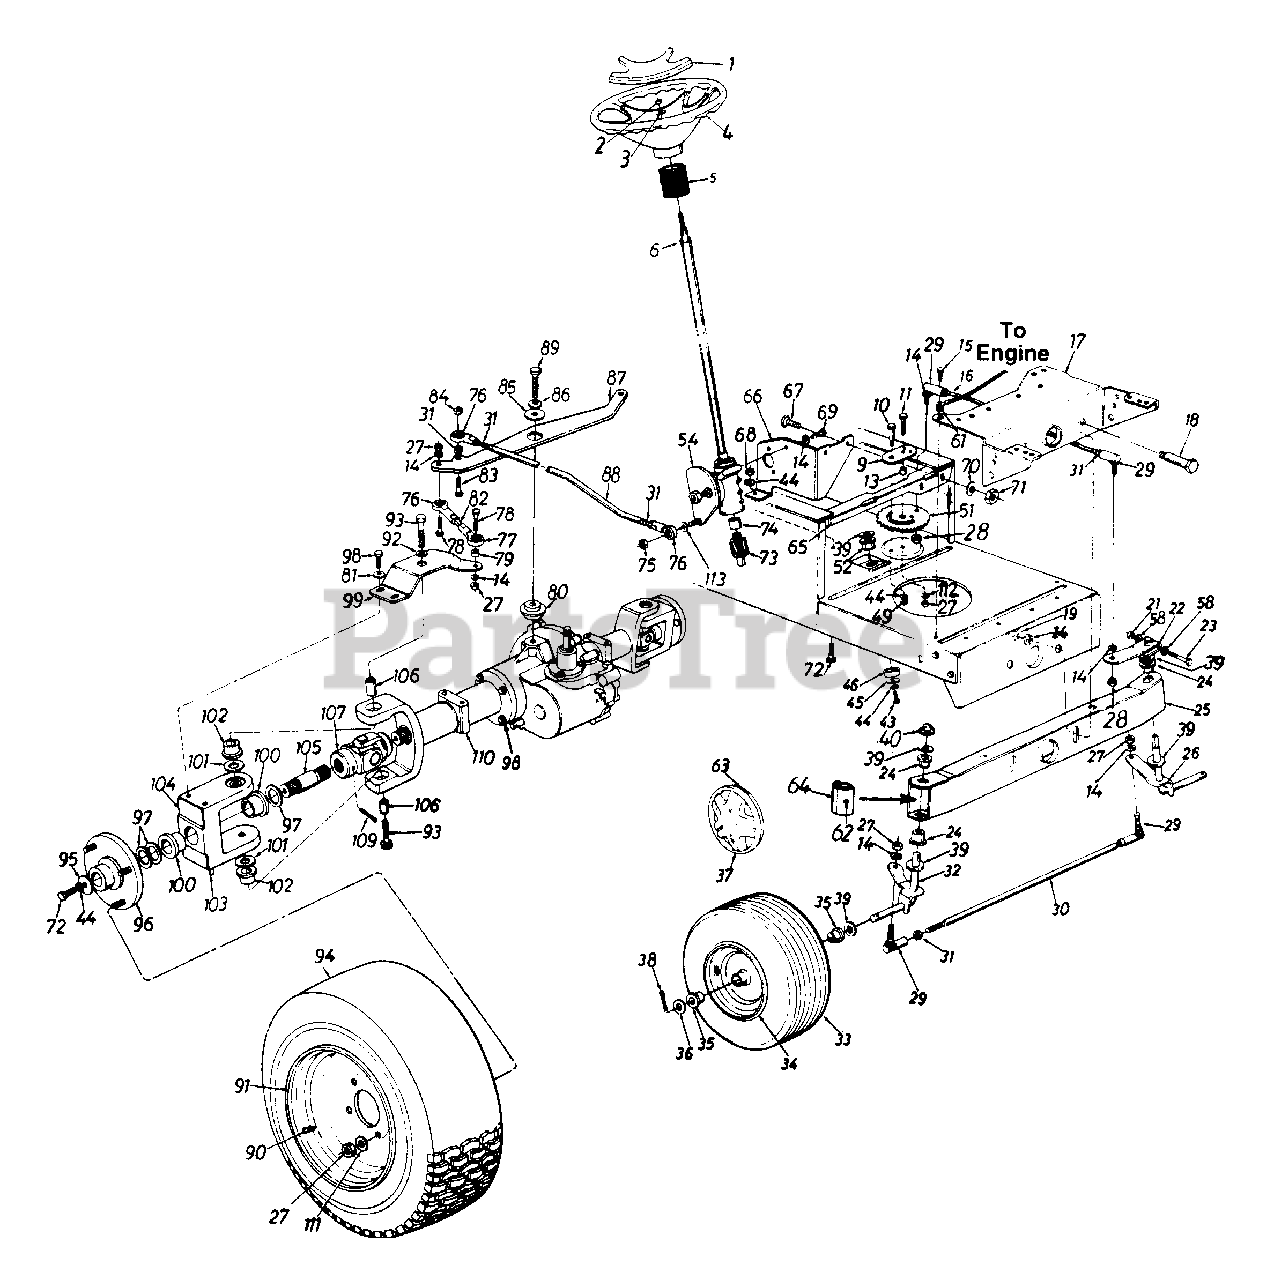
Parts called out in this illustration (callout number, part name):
1	Steering Wheel Cap
2	Hex L-Nut 5/16-24 Thd.
3	Belleville Wash. .345" I.D.
4	Steering Wheel
5	Steering Bellow
6	Steering Shaft Ass'y.
9	Retainer Plate
10	Shoulder Bolt .437" Dia. x .35" Lg. 5/16-18 Thd.
11	Hex Bolt 3/8-24 x 1.0" Lg. (Grade 5)
13	Spacer .380" I.D. x .625" O.D. x .227"
14	L-Wash. 3/8" I.D.
15	Hex Wash. Hd. Self-Tap Scr.
16	Steering Drag Link
18	Shoulder Bolt .498" Dia. x 2.04" Lg. 3/8-16 Thd.
19	Hex Nut 3/8-16 Thd.
21	Hex Cent. L-Nut 5/16-24 Thd.
22	Steering Arm Front Axle
23	Hex Bolt 5/16-24 x 2.00" Lg. (Grade 5)
24	Hex Flg. Brg. .634" I.D.
26	Front Axle Ass'y. - L.H.
27	Hex Nut 3/8-24 Thd.
28	Hex Jam Nut 3/8-24 Thd.
29	Ball Joint 3/8-24 Thd.
31	Hex Jam Nut 3/8-24 Thd.
32	Front Axle Ass'y. - R.H.
35	Ball Bearing
36	Fl-Wash. .635" I.D. x 1.59" O.D.
37	Front Hub Cap
38	Cotter Pin 1/8" Dia. x 1.25" Lg.
39	Fl-Wash. .640" I.D. x .24" O.D.
43	Hex L-Bolt 5/16-18 x .62"
44	L-Wash. 5/16" I.D.
45	Fl-Wash. .33" I.D. x 1.25" O.D.
46	Spacer (Plastic)
49	Hex L-Nut 5/16-18 Thd.
51	Steering Gear Segment
52	Hex Flg. Brg. .634 I.D.
54	Steering Ass'y. Comp.
58	Wave Wash. .32" I.D. x .62"
61	Ext. L-Wash. 5/16" I.D.
62	Grease Fitting
63	Spring Clip
64	Pivot Bar End Cap
65	Horizontal Cross Bracket
66	Vertical Mounting Bracket
67	Hex Bolt 1/4-28 x .75" Lg.
68	Hex Nut 5/16-24 Thd.
69	Hex Bolt 3/8-16 x 1.0" Lg.
70	Bell-Wash. .265" I.D. x .75"
71	Hex Nut 1/4-28 Thd.
72	Hex Bolt 5/16-24 x .75" Lg.
73	Pinion Shaft
74	Steering Shaft Splined Coupler
75	Hex L-Nut 3/8-24 Thd.
76	Rod End 3/8-24 Thd - R.H.
77	Rod End 3/8-24 Thd. - L.H.
78	Hex Bolt 3/8-24 x 1.5" Lg. (Gr 5)
79	Spacer .38" I.D x 625"
80	Shld. Spacer .51" I.D.
81	Bell-Wash. .38" I.D. x .88"
83	Hex Bolt 3/8-24 x 1.25" Lg.
84	Hex Patch L-Nut 3/8-24 Thd.
85	Fl-Wash. .531" I.D. x 1.75"
86	Bell-Wash. .505" I.D. x 1.0"
89	Hex Bolt 1/2-13 x 1.5" Lg. (Gr. 5)
90	Air Valve
93	Hex Bolt 1/2-20 x 1.75" Lg. (Gr. 5)
95	Fl-Wash. .33" I.D. x 1.25"
96	Wheel Flange Ass'y.
97	Fl-Wash. 1.0" x 1.56"
98	Hex Bolt 3/8-24 x 1.25" Lg.
101	Fl-Wash. .76" I.D. x 1.5"
102	Flange Brg. 3/4" I.D.
103	Grease Fitting
104	Wheel Brg. Housing
106	Pivot Sleeve
109	Grooved Roll Pin 1.0" Lg.
110	Axle Horn Ass'y.
111	Bell-Wash. .38" I.D. x .88"
112	Bell-Wash. .39" I.D. x 1.38"
113	Fl-Wash. .385" I.D. x .62"
